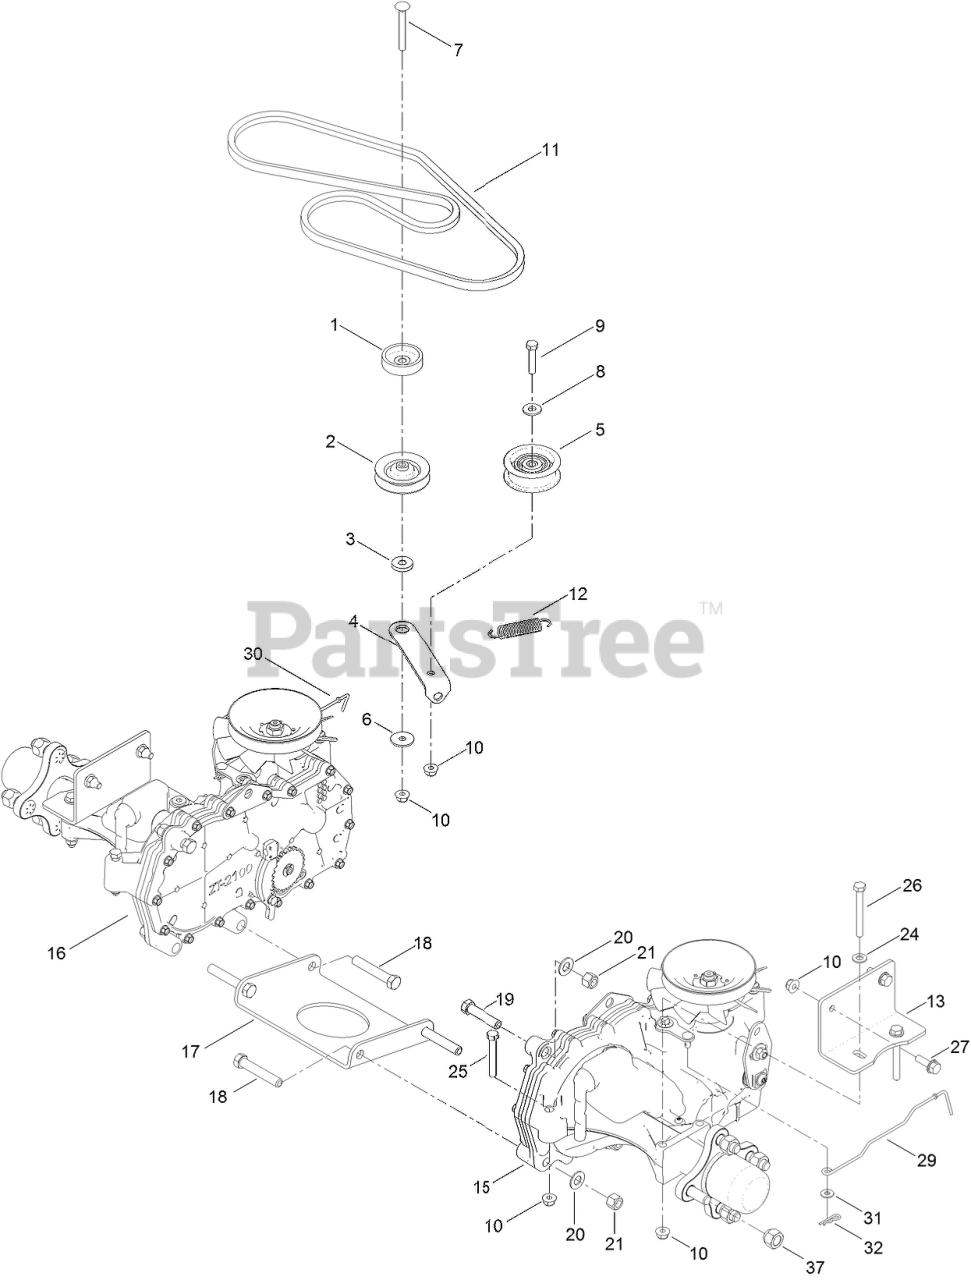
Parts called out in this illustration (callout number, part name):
1	SPACER
2	PULLEY-IDLER
3	SPACER-ARM, IDLER
4	ARM-IDLER
5	PULLEY-IDLER
6	WASHER-PIVOT
7	SCREW-CARR
8	WASHER-FLAT
9	SCREW-HH
10	NUT-HF, NI
11	V-BELT
12	SPRING-RETURN, PEDAL
13	MOUNT-HYDRO
15	LH HYDRO TRANSAXLE ASM
16	RH HYDRO TRANSAXLE ASM
17	PLATE-CROSS, HYDRO
18	SCREW-HH
19	SCREW-HH
20	WASHER-FLAT
21	NUT-LOCK, NI
24	WASHER-PLAIN
25	SCREW-HH
26	SCREW-HH
27	SCREW-HHF
29	ROD-BYPASS, LH
30	ROD-BYPASS, RH
31	WASHER
32	PIN-COTTER
37	NUT-LUG
